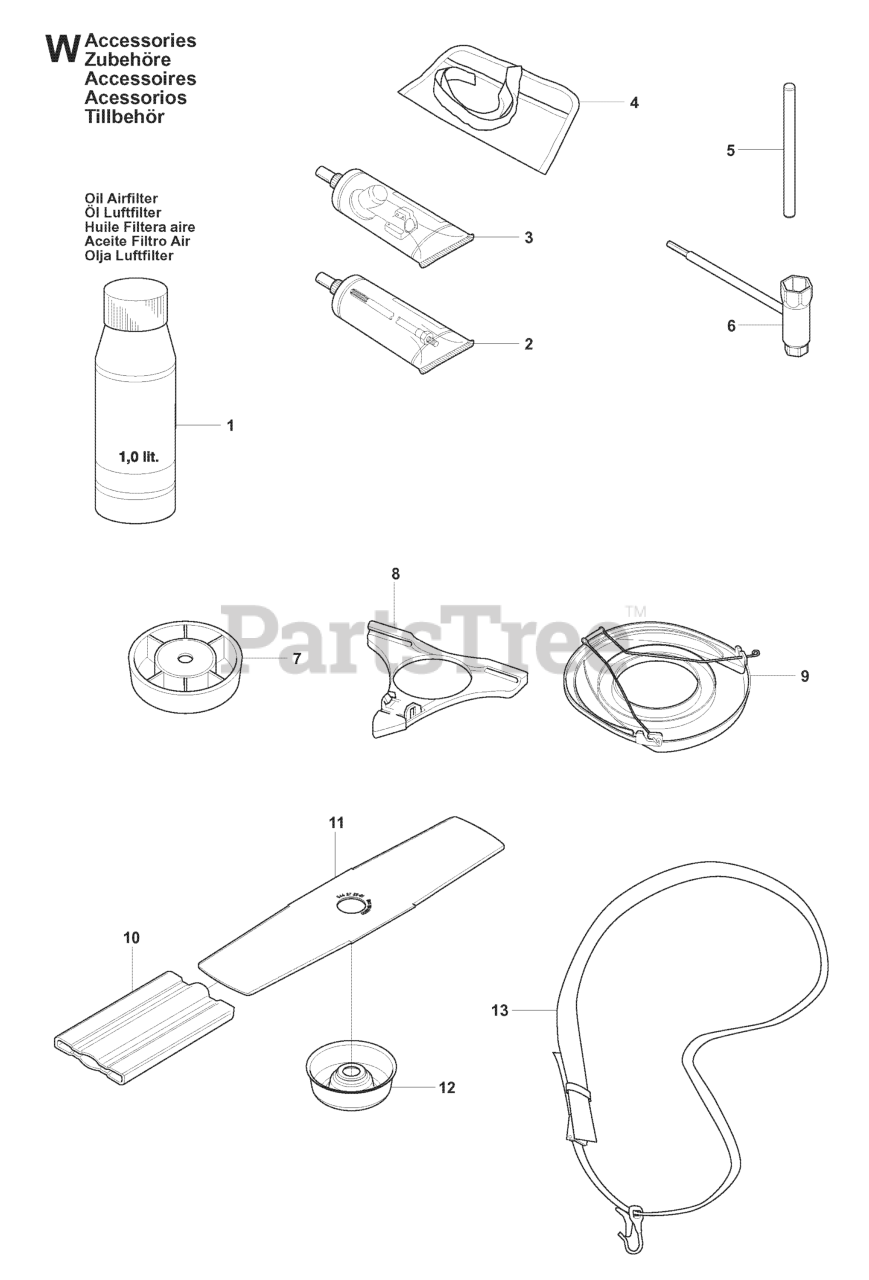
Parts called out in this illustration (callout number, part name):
1	Air Filter Oil 1l.
2	DRIVE SHAFT GREASE (200 G)
3	BEVEL GEAR GREASE
5	LOCKING PIN
6	RP COMBI TOOL
7	SUPPORT CUP
8	TRANSPORT GUARD
9	BLADE GUARD TRANSPORT
12	SUPPORT CUP
13	Harness-w/o warning
